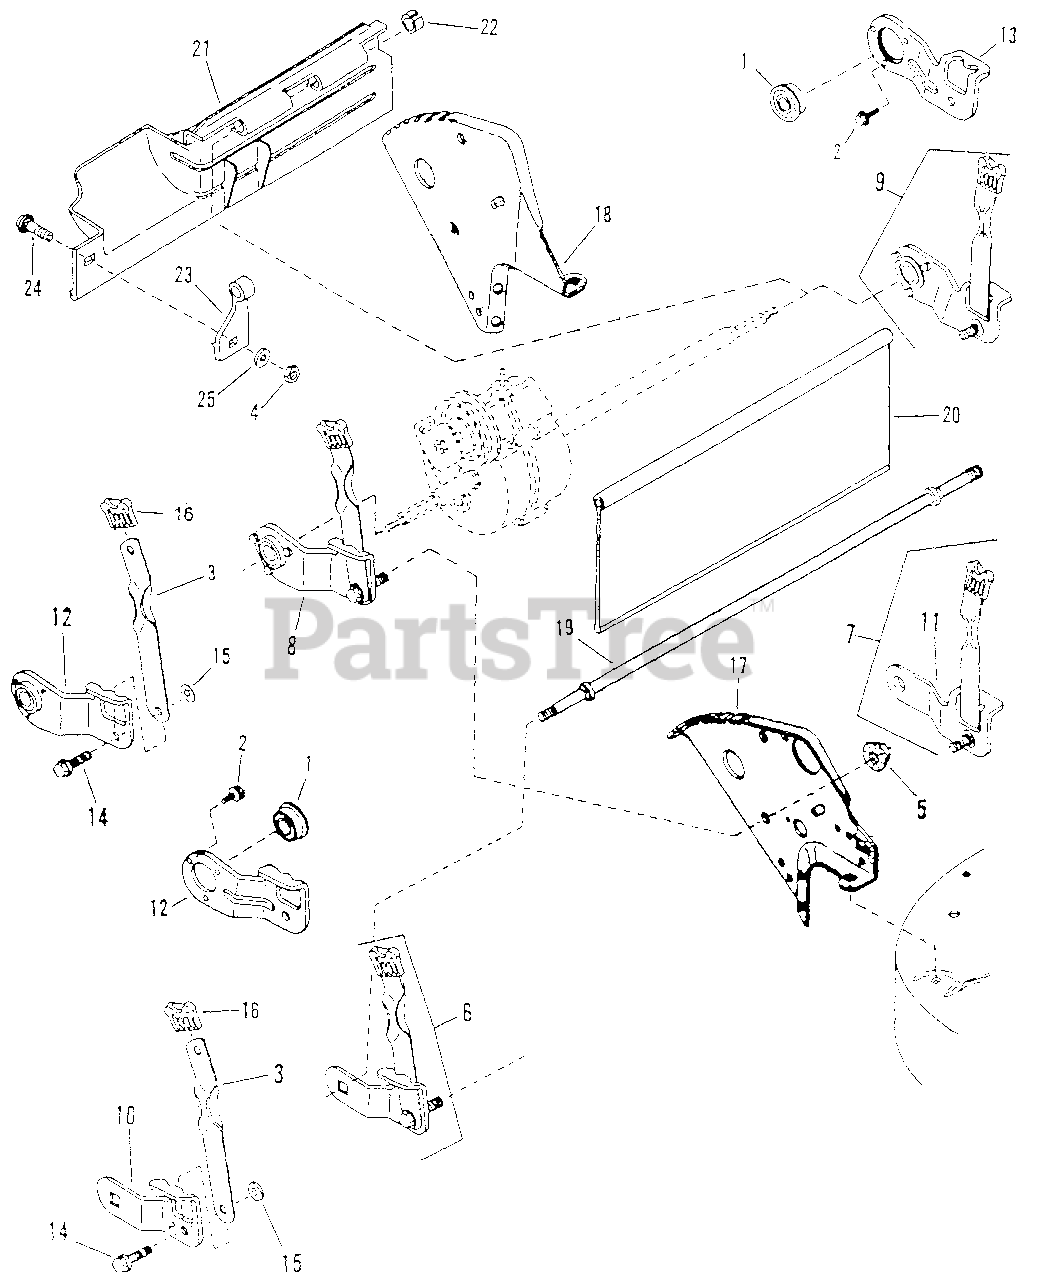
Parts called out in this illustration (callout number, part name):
1	BEARING, 9/16" V21
2	SCREW, #10-32 x 3/8" Hex Washer Self-Tap (Torx)
3	LATCH, Height Adjusting (Long)
4	NUT, 1/4-20 Hex, Grade 5
5	NUT, 5/16-18 Hex Flange Lock, Grade 5
6	ASSEMBLY, Wheel Arm
7	ASSEMBLY,
8	ASSEMBLY, Wheel Arm (Right Rear)
9	ASSEMBLY, Wheel Arm (Left Rear)
10	ARM, Round Axle End
11	ARM, Square Axle End
12	ARM, Wheel Right Rear
13	ARM, Wheel Left Rear
14	BOLT, 5/16-18 x 1" Shoulder
15	RETAINER, 5/16" Bolt
16	GRIP, Latch
17	BRACKET, Right Rear Wheel
18	BRACKET, Left Rear Wheel
19	AXLE
20	GUARD, Rear Foot
21	GUARD, Rear Foot
22	RING
23	SUPPORT, Foot Guard
24	BOLT, 1/4-20 x 1/2" Short Neck Carriage, Grade 5
25	WASHER, 1/4" Internal Tooth Lock
